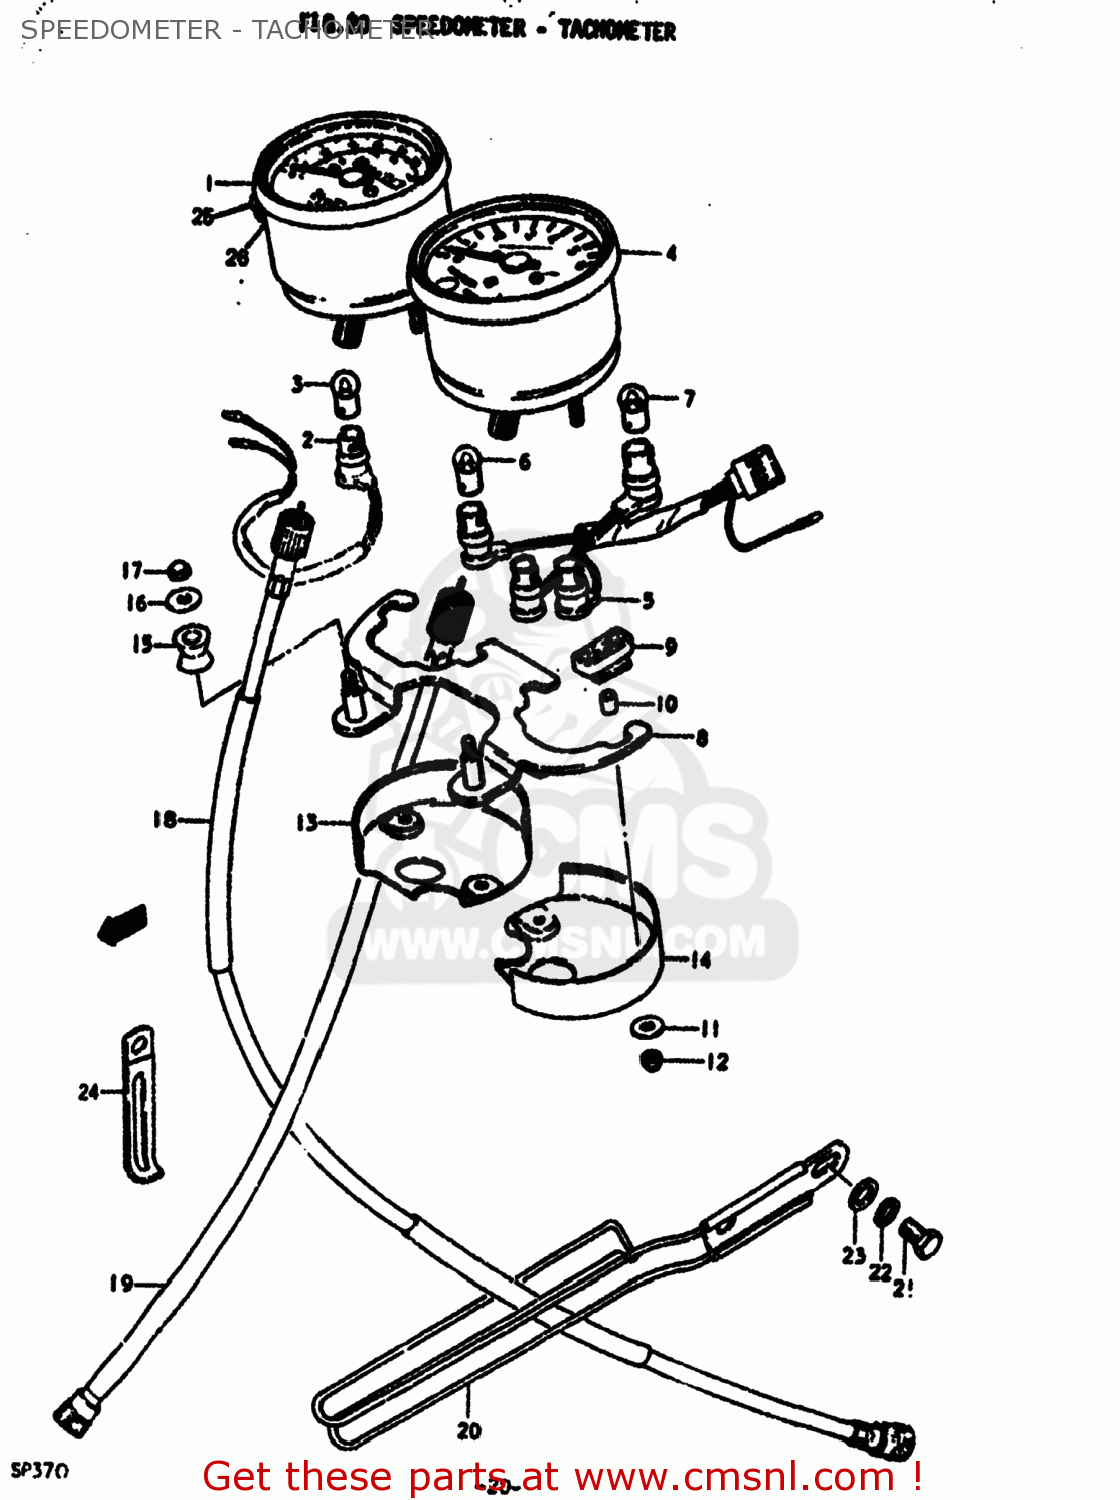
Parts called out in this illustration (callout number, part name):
0	SPEEDOMETER ASSEMBLY
1	SPEEDOMETER ASSEMBLY
2	SOCKET,METER
3	BULB(6V/3W)
4	TACHOMETER
5	SOCKET,TACHOMETER
6	BULB(6V1.7W,STANLEY,A61A)
7	BULB(6V/3W)
8	BRACKET,COMBINATION METER
9	CUSHION
10	SPACER
11	WASHER (5.5X16X1.2)
12	NUT
13	COVER,METER,UNDER
14	PLATE,TACHOMETER UNDER
15	CUSHION
16	WASHER
17	NUT
18	CABLE ASSY,SPEEDOMETER
19	CABLE ASSEMBLY,TACHOMETER
20	GUIDE,CABLE
21	BOLT 8X12
22	LOCK WASHER
23	WASHER
24	CLAMP L:35
26	SCREW
